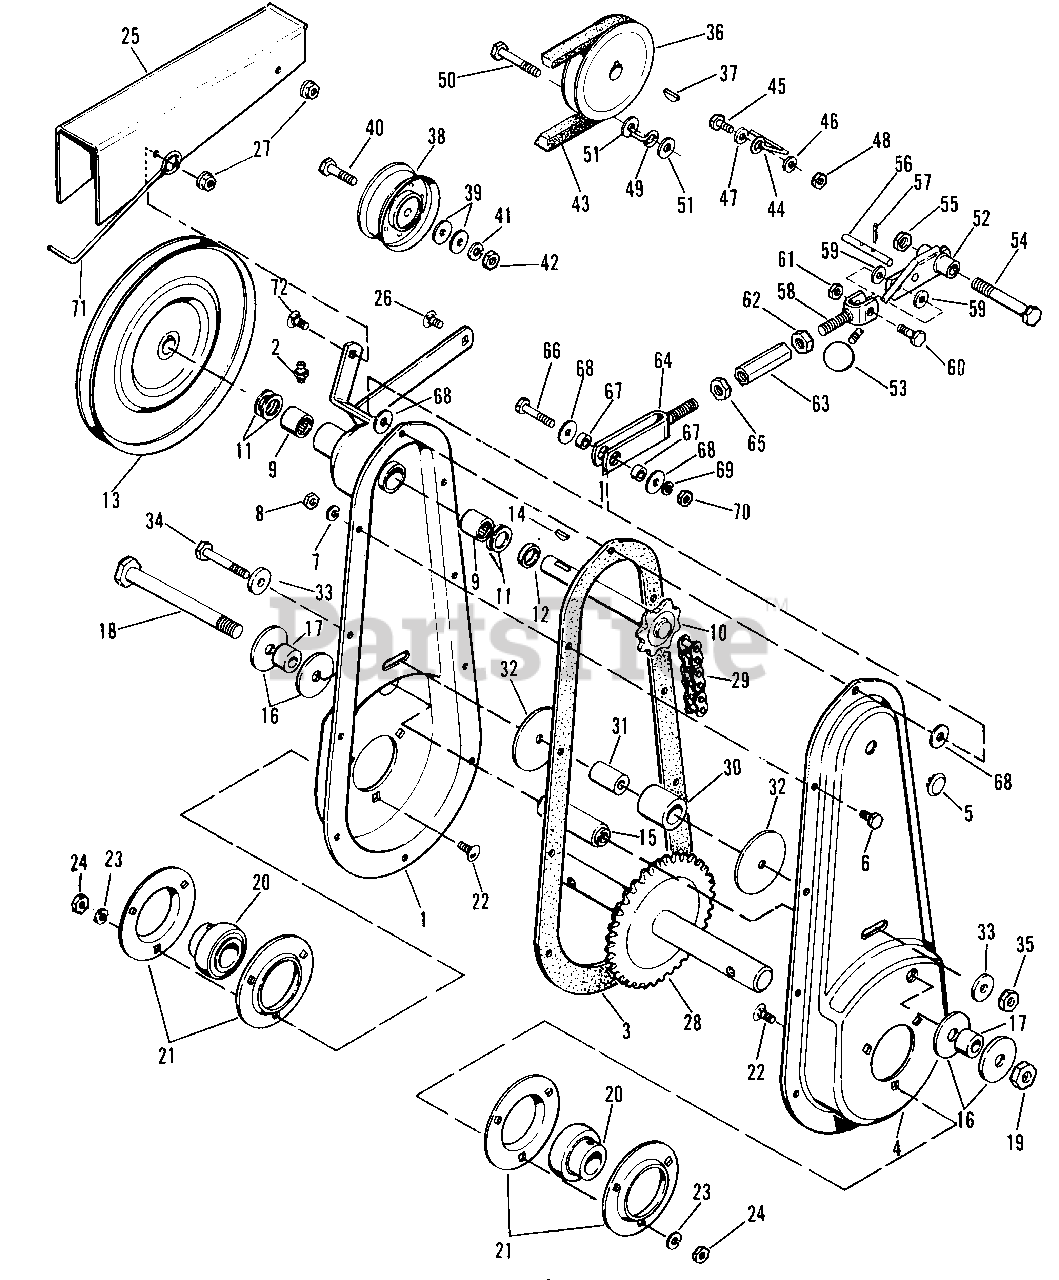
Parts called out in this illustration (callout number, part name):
1	CASE ASSY., L.H.
2	FITTING, Grease, 1/4-28
3	GASKET, Case
4	CASE ASSY., R.H.
5	BUTTON, Plug
6	CAPSCREW, Hex, 5/16-18 x 5/8"
7	LOCKWASHER, 5/16
8	NUT, Hex, 5/16-18
9	BEARING, Needle
10	DRIVE SHAFT ASSY.
13	PULLEY (Driven)
14	KEY, Woodruff 3/16 x 3/4
15	SPACER, Case
18	CAPSCREW, Hex, 1/2-13 x 5-1/2"
19	LOCKNUT, 1/2-13
21	FLANGE, Bearing
22	BOLT, Carriage, 5/16-18 x 3/4"
23	LOCKWASHER, 5/16
24	NUT, hex, 5/16-18
25	GUARD, Belt
26	BOLT, Carriage, 5/16 18 x 1/2
27	NUT, Special, 5/16-18
28	TlNE SHAFT ASSY.
33	WASHER, Special
34	CAPSCREW, Hex, 3/8-16 x 2-1/4"
35	LOCKNUT, hex, 3/8-16
36	PULLEY (Driver)
37	KEY, Woodruff, 3/16-3/4
38	PULLEY, Idler
39	WASHER, Plain, 5/16
40	CAPSCREW, Hex, 3/8-16 x 1-1/4" lg.
41	LOCKWASHER, 3/8
42	NUT, hex, 3/8-16
43	BELT, "V"
44	STOP, Belt
45	CAPSCREW, Hex, 5/16-18 x 3/4"
46	LOCKWASHER, 5/16
47	WASHER, Plain, 1/4
48	NUT, hex, 5/16-18
50	CAPSCREW, Hex, 3/8-16 x 1-3/4"
51	WASHER, Plain, 5/16
52	CLUTCH LEVER ASSY.
54	CAPSCREW, Hex, 7/16-14 x 2-3/4
55	LOCKNUT, hex, 7/16-14
56	PIN, Stop
57	PIN, Cotter, 3/32 x 3/4
58	CLEVIS ASSY., L.H.
59	WASHER, Nylon
60	CAPSCREW, Hex, 5/16-18 x 1"
61	LOCKNUT, hex, 5/16-18
62	NUT, Hex, 7/16-14 L.H. Thread
63	TURNBUCKLE
64	YOKE ASSY., R.H.
65	NUT, Hex, 7/16"-14
66	CAPSCREW, Hex, 5/16-18 x 1-1/2"
68	WASHER, Plain, 5/16
69	LOCKWASHER, 5/16
70	NUT, Hex, 5/16-18
71	STOP, Belt
72	BOLT, Carriage, 5/16-18 x 3/4"
